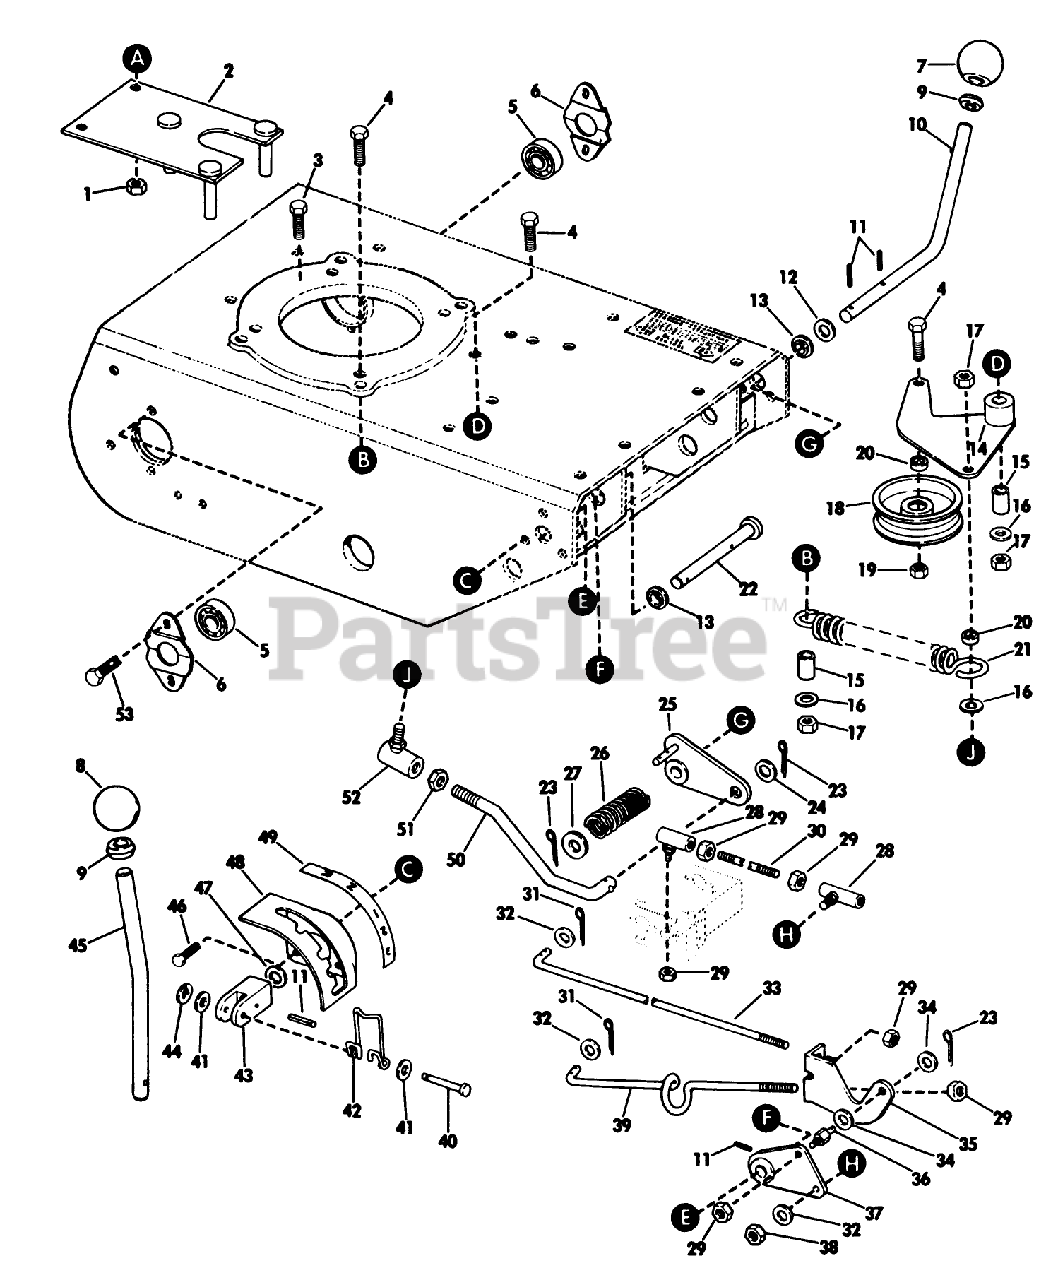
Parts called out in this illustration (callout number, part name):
2	Belt Keeper Assembly
29	STOP NUT
38	STOP NUT
